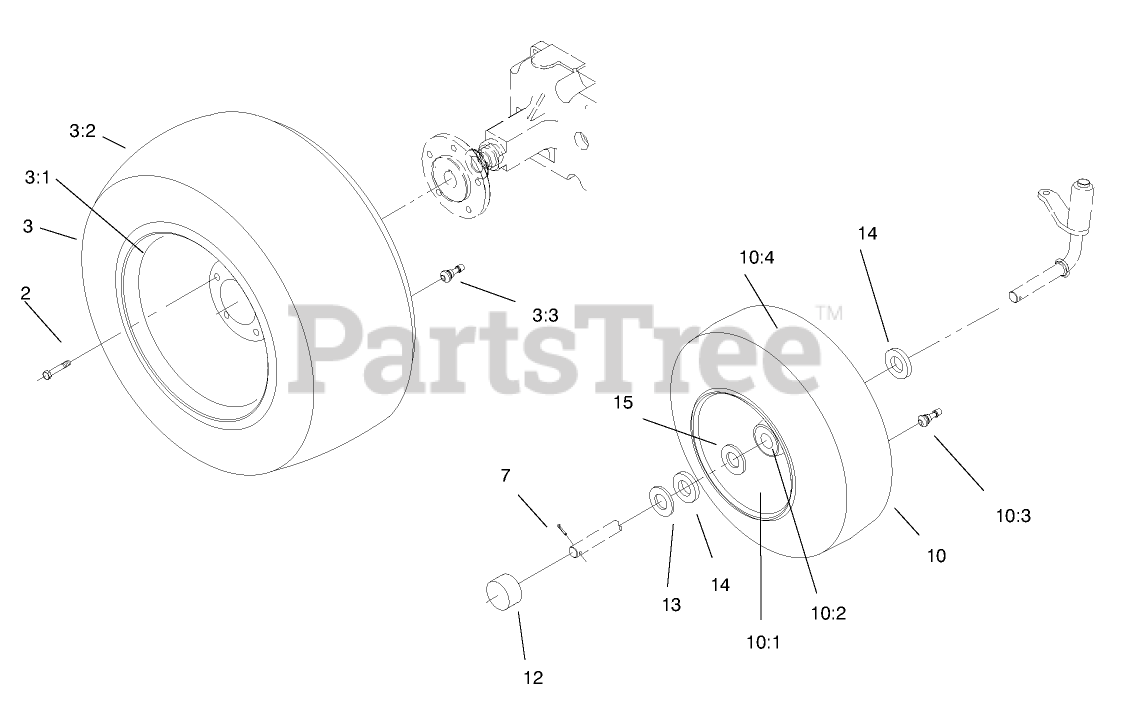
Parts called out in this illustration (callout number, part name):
2	BOLT-LUG
3	Wheel/Tire ASM-Rear
3:1	WHEEL
3:3	VALVE
7	PIN-COTTER
10	ASM-Wheel Tire
10:1	TIRE-15 X 6.00-6
10:3	Wheel
10:4	ZERK-GREASE
10:5	VALVE
10:6	BEARING-WHEEL
12	CAP-HUB
13	WASHER-PLAIN
14	WASHER
15	WASHER-SHIM
